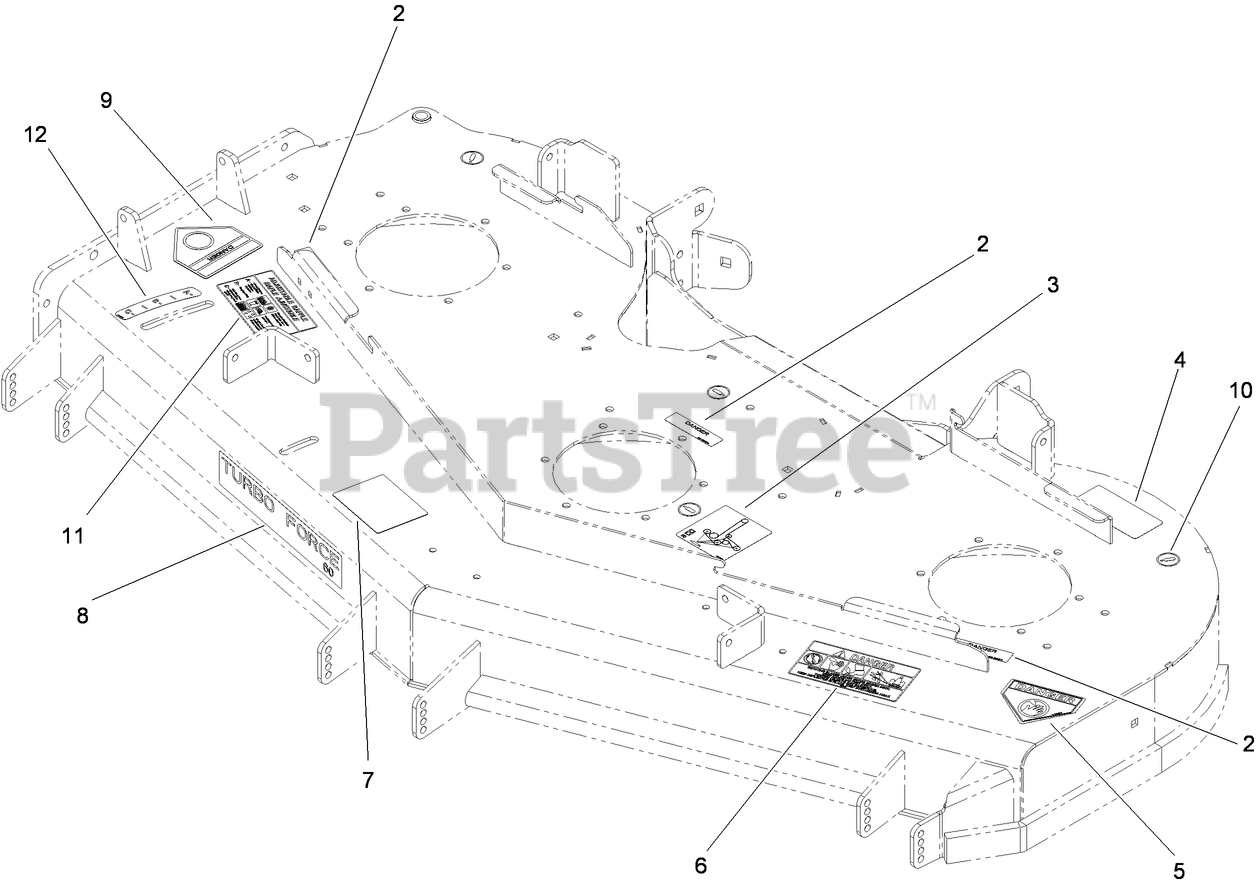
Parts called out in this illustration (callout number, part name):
2	DECAL-COVER, MISSING
3	DECAL-ROUTING, DECK BELT
4	DECAL-TORQUE
5	DECAL-DANGER
6	DECAL-DANGER, THROWN OBJECT
7	DECAL-SCALP, ANTI
9	DECAL-DANGER
10	DECAL-GREASE
11	DECAL-ADJUSTMENT, BAFFLE
12	DECAL-SETTING, BAFFLE
